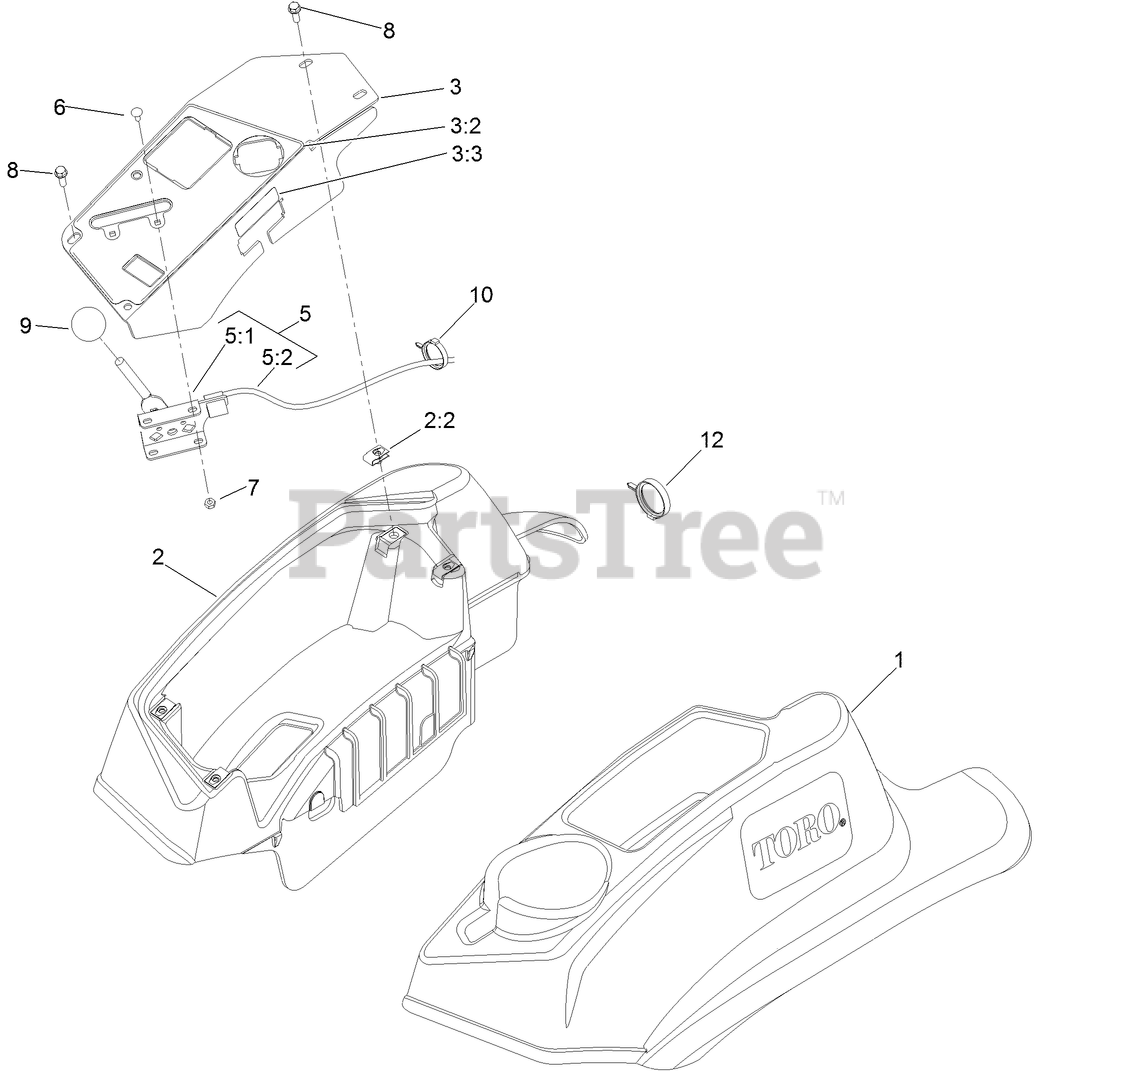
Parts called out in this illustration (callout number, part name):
1	CONSOLE-LH
2	RH CONSOLE ASM
3	CONTROL PANEL W/DECAL ASM
3:2	DECAL-PANEL, CONTROL
3:3	DECAL-FUSES
5	THROTTLE CONTROL ASM
5:1	LEVER-THROTTLE
5:2	CABLE-THROTTLE
6	BOLT-CARR
7	NUT-LOCK, NI
8	SCREW-HWH
9	KNOB-BALL
10	CLAMP-HOSE
12	CLAMP-HARNESS
